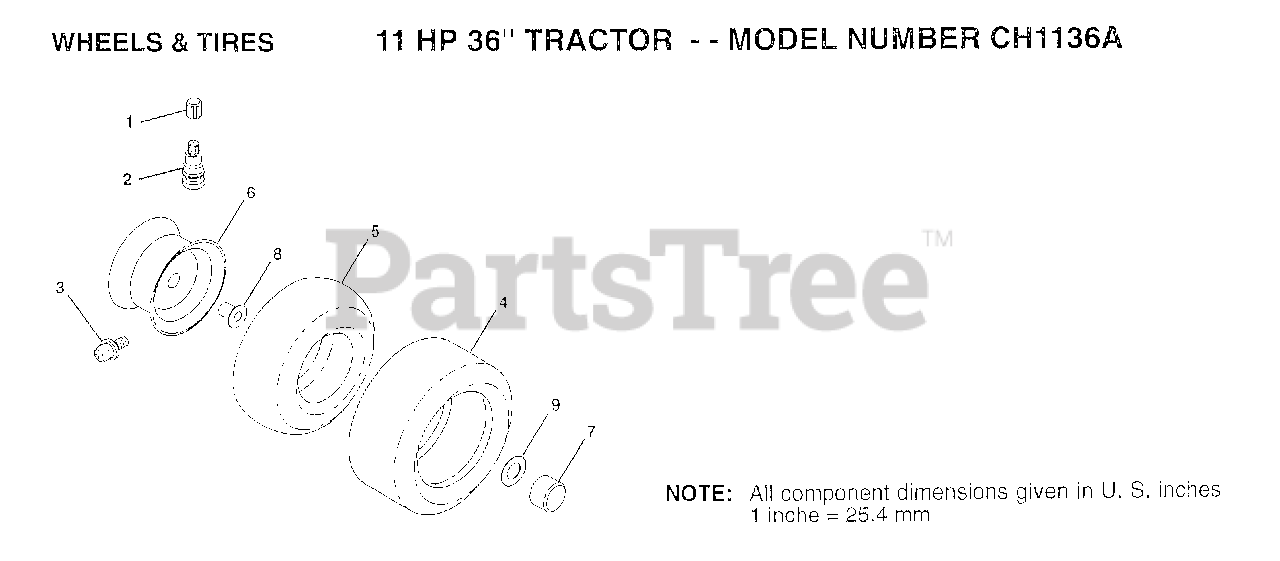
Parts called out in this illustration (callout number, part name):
1	VALVE CAP
2	VALVE STEM LT
3	FITTING LT
5	TUBE.5.3/4.5/6
5	TUBE.16X6.5/7.5-8
6	"RIM ASM REAR 8"""
7	HUB CAP
8	"FLANGE, BEARING"
9	WASHER
